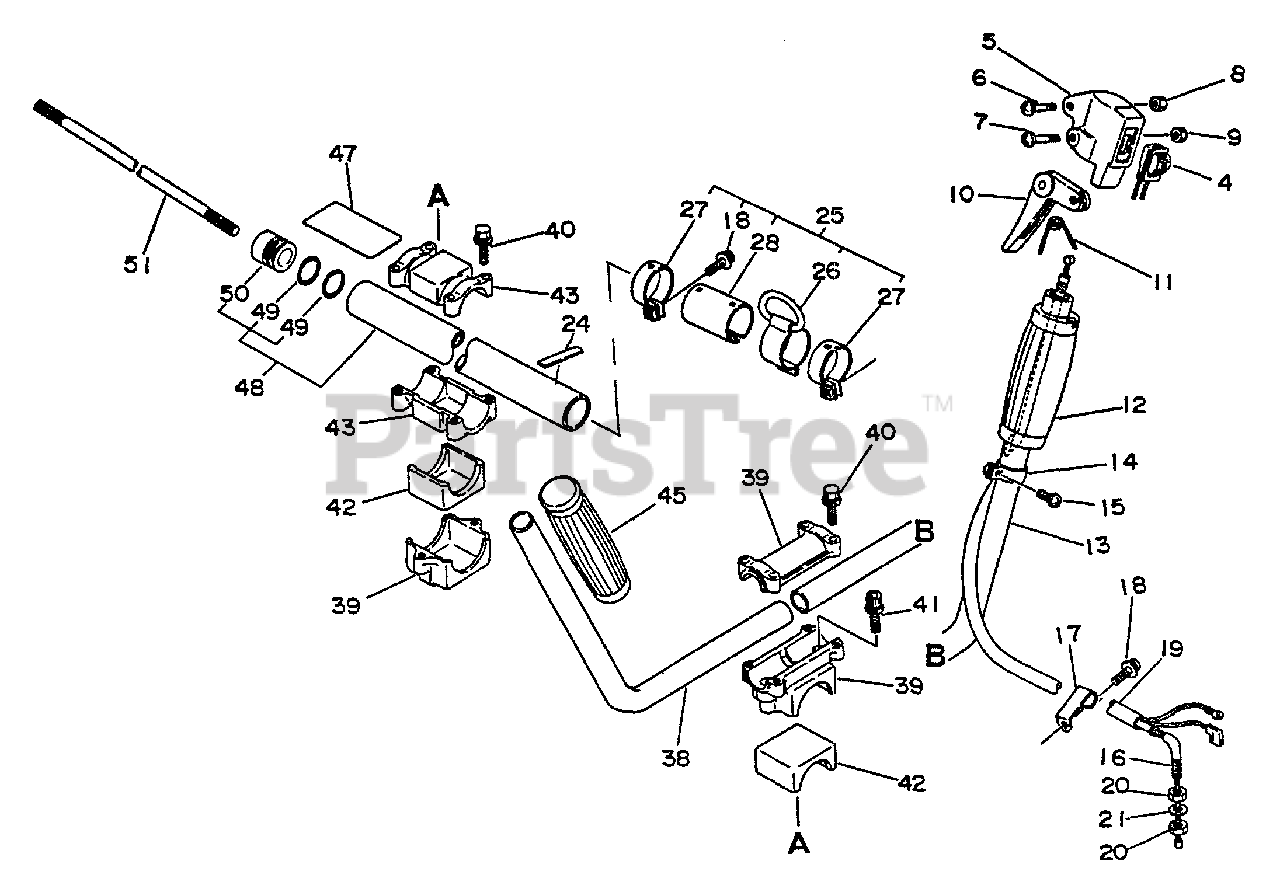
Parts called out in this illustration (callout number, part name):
4	SWITCH, ON-OFF
5	BRACKET, THROTTLE
7	SCREW 5×25
8	LOCKNUT - 5
9	NUT M5
10	TRIGGER, THROTTLE
15	SCREW 5×10
16	CABLE, THROTTLE
18	SCREW 5×14
19	TUBE
21	WASHER 6.5×11.5×0.8
24	LABEL - ALIGNMENT
25	HANGER ASSY
25	HOOK
26	CLAMP
27	COLLAR
28	COLLAR
38	HANDLE, LEFT
39	BRACKET ASSY
40	BOLT - 5×25
41	BOLT 5×25
42	CUSHION
43	BRACKET KIT
45	GRIP, HANDLE
47	LABEL - CAUTION
48	MAIN PIPE ASSY
50	BUSHING
51	DRIVESHAFT
